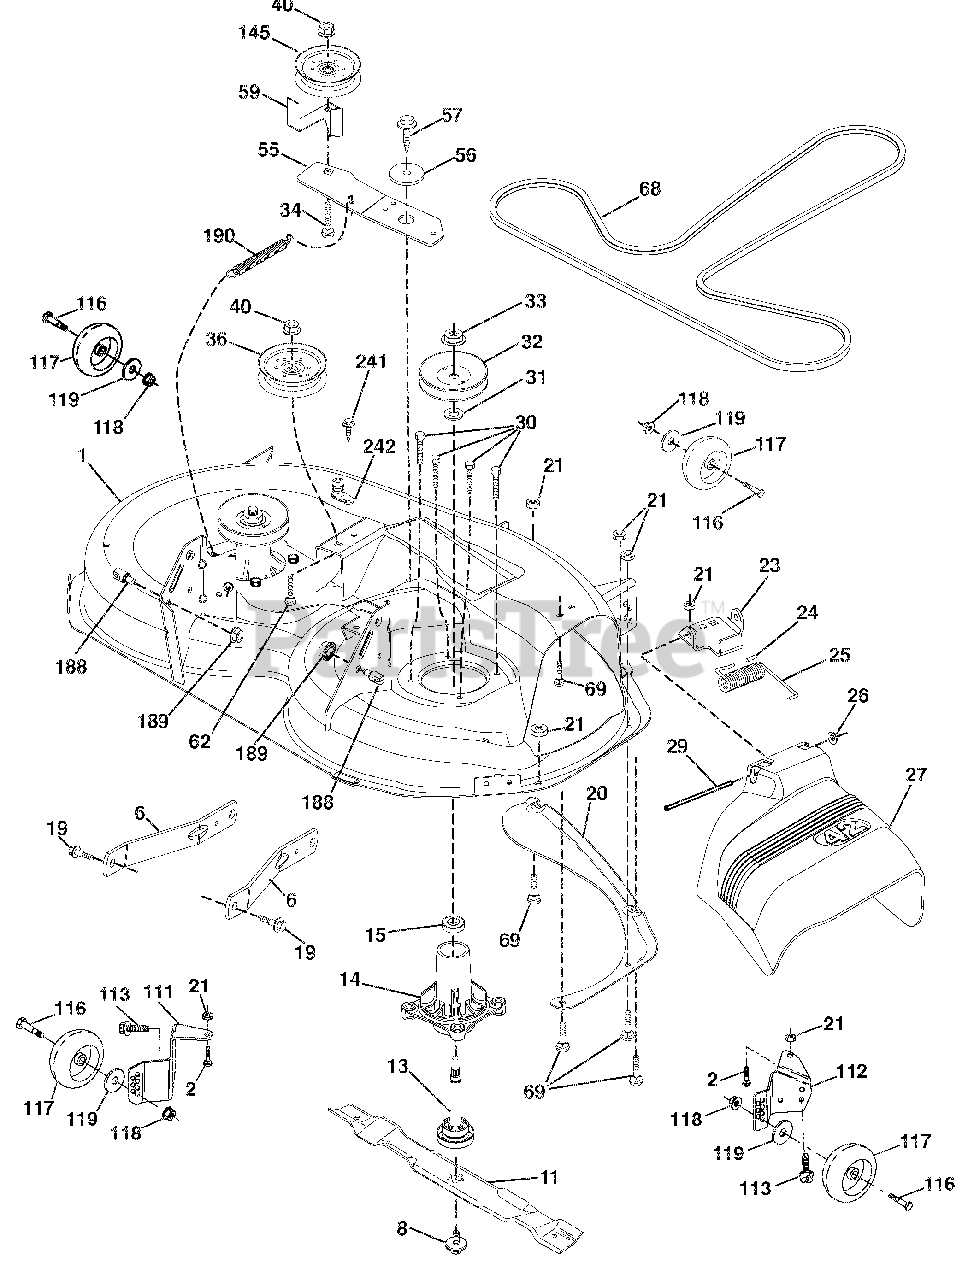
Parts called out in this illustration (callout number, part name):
1	MOWER HOUSING
6	ARM.SUSPENSION.MOWER.REAR.LD
8	BOLT/WASHER ASM.7/16-20.UNF
11	BLADE.MOWER.42"HI LIFT PREMIUM
13	SHAFT ASM.MNDRL.N/GREASEABLE38
14	HOUSING.MANDREL.4PT.SERVICE
15	BEARING.BALL.MANDREL
19	BOLT.SHOULDER
20	BAFFLE.VORTEX.42.STD/HEAVY DTY
21	Nut, Hex, Crownlock 5/16-18
23	BRACKET.DEFLECTOR.38/42"2005
24	CAP.SLEEVE..80X.112.BLK.MOWER
25	SPRING.TORSION.DFL.38/42/46.GR
26	NUT.PUSH.PHOS.& OIL
27	SHIELD.DEFLECTOR.
29	ROD.HINGE.42/46"
30	SCREW.THD ROLL.DOD PT.HEX
31	WASHER.SPACER.MANDREL
32	MANDREL.PULLEYS.42,44,50
33	NUT.FLANGE.LOCK.TOP
34	BOLT.CARR.SH.3/8-16X1-1/2.GR5
36	PULLEY.IDLER.4.50.RAW
40	Nut, Hex, Flangelock 3/8-16
55	IDLER.ARM
56	SPACER.RETAINER
57	SCREW.3/8-16X1.SMGML.TAP/R.BLK
59	GUARD.TUV.IDLER
62	BOLT.RD.HD.SQ.NK.3/8-16UNC X 2
68	V-Belt, 42" Mower
69	BOLT.RDHD.SQNK.5/16-18 X 5/8
111	BRACKET WHEEL GAUGE LH
112	BRACKET WHEEL GAUGE RH
113	BOLT.5/16-18HEX.WHS.HD.LCKSERR
116	BOLD SHLD "A" 2.41 "B" 1.66
117	WHEEL.GAGE.HALF.SPOKED
118	Nut, Hex, Flangelock 3/8-16
119	Washer 3/8 x 7/8 x 14 Ga.
145	PULLEY.IDLER 48"PRIMARY
188	STUD.FASTNER.W/'D'ANTI-ROTATIO
189	Nut, Lock Hex Flange 5/16-18 u
242	PORT WASHOUT
